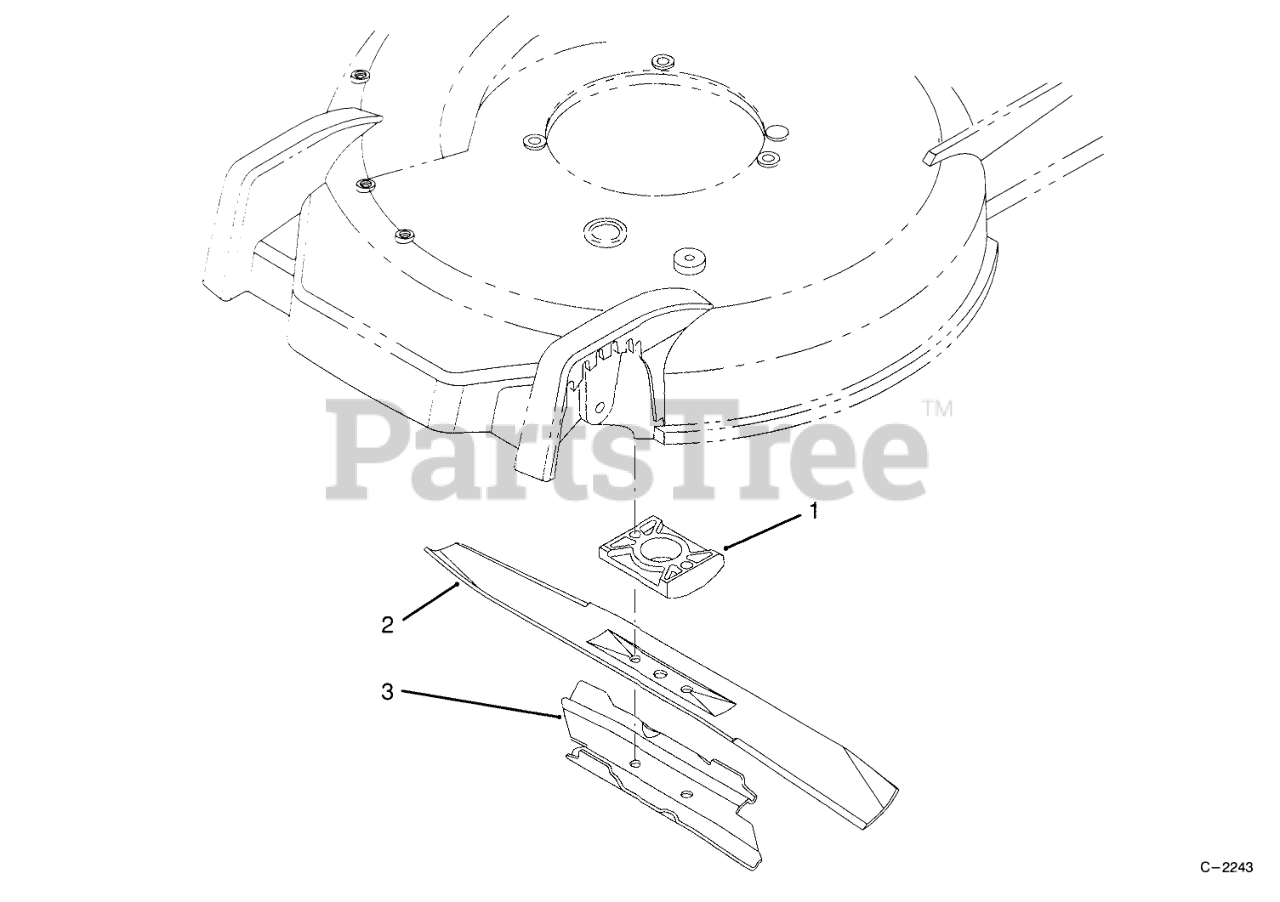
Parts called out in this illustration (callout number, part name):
1	SPACER - BLADE
2	Blade
3	Stiffener-Blade
